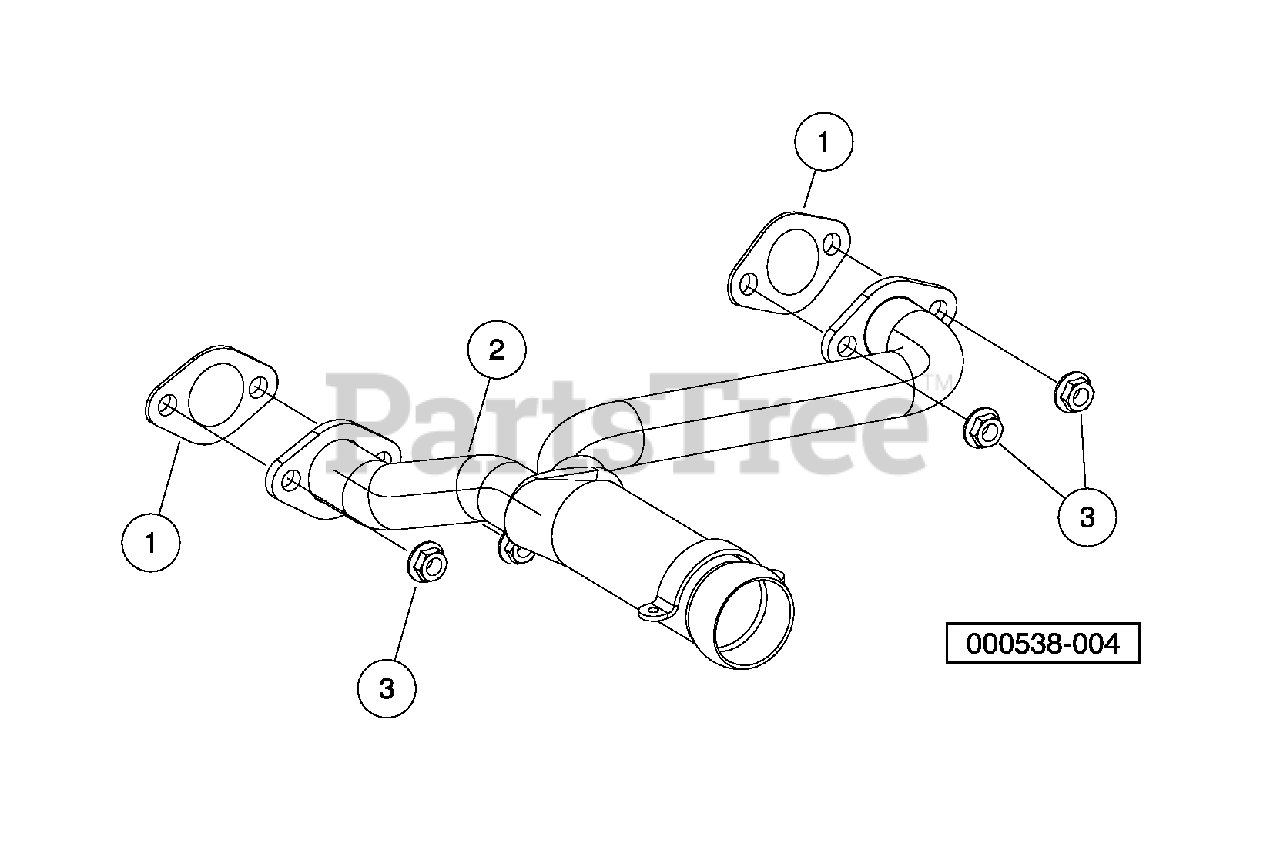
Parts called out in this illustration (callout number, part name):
1	Gasket, Exhaust Header, Fh680d
2	Header, Exhaust, Gas, Fh680d
3	Nut Flg, M8 X 1.25 Serrated
